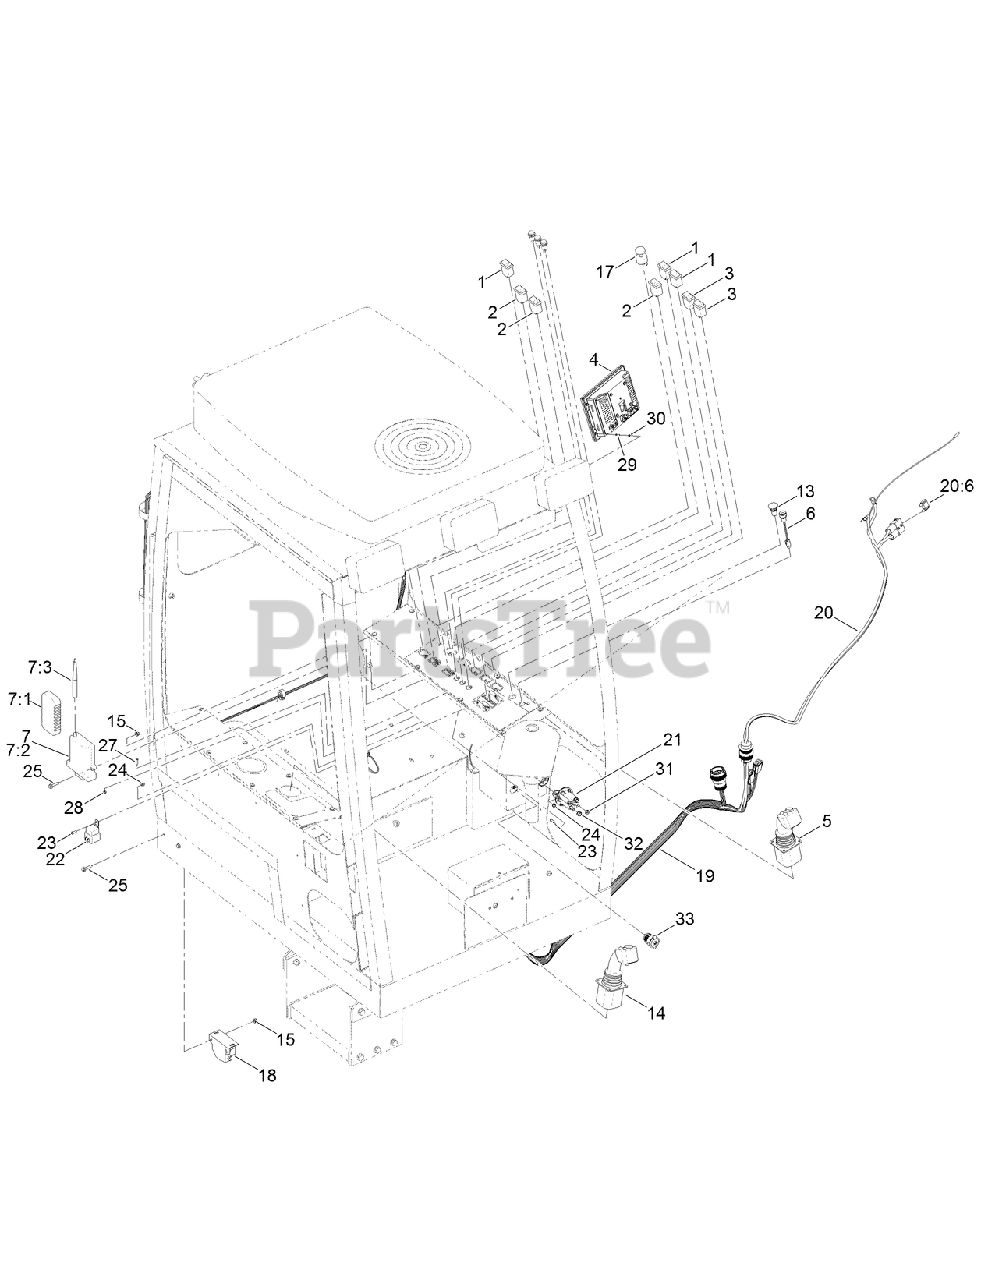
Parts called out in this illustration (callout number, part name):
1	SWITCH-ROCKER, 2 POLE (ON/OFF)
2	SWITCH-ROCKER, 2 POLE
3	SWITCH-ROCKER, 1 POLE (ON)OFF/ON(OFF)
4	DISPLAY-DP610TM, UNPROGRAMMED
5	JOYSTICK-MODIFIED (LEFT HAND)
6	SWITCH-START, GREEN BUTTON
7	LONG RANGE EXIT SIDE LOCKOUT KIT
7:1	HANDHELD-RANGE, LONG
7:2	BASE UNIT-RANGE, LONG
7:3	ANTENNA-LOCKOUT
13	BUTTON-PUSH, RED MUSHROOM
14	JOYSTICK-CARRIAGE
15	NUT-FLANGE, NI
17	SWITCH-WIPER
18	ALARM-BACKUP
19	HARNESS-WIRE, CAB
20	HARNESS-WIRE, CAB POWER
20:6	FUSE-MAXI, 60 AMP
21	SOLENOID
22	RELAY
23	SCREW-HSBH
24	NUT-HF
25	SCREW-HHF
27	SCREW-HSBH
28	NUT-HHF
29	SCREW-PH
30	NUT-LOCK, NI
31	NUT-KEPS
32	NUT-KEPS
33	RECEPTACLE-12V
